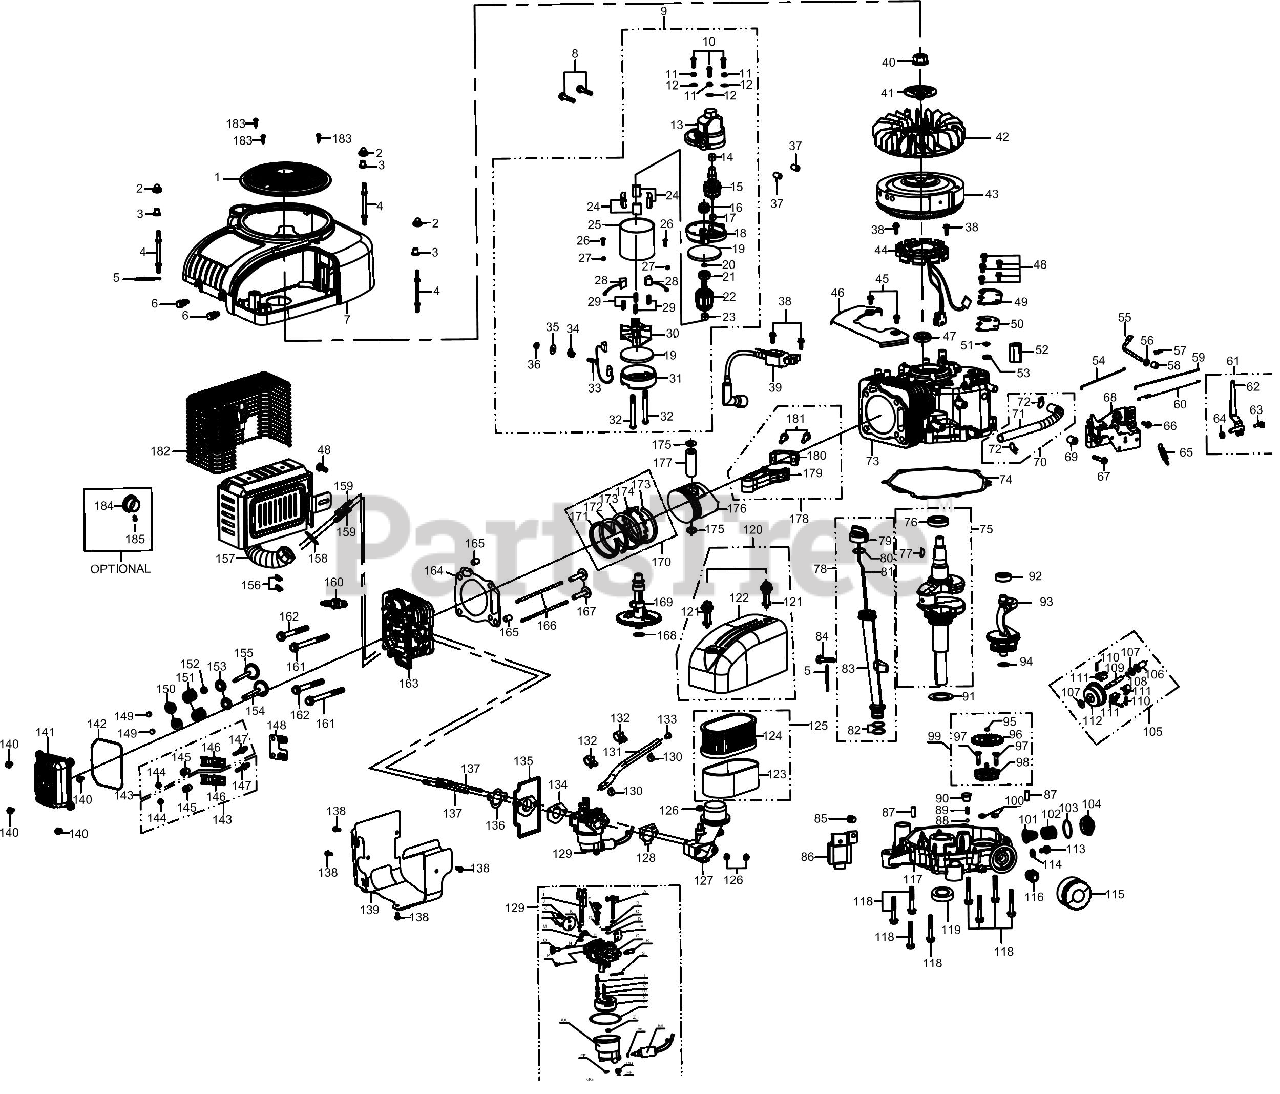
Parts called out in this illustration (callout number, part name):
1	Shroud
2	Nut,M6
3	Bush, 16x12-10x6.5
4	Stud, M6x99
5	Clip
7	Engine Shroud
8	Bolt, M8x40
9	Electric Starter
13	Electric Starter Cover
14	Bearing
15	One-way Clutch
16	Spline Gear
17	Bearing
18	Electric Starter Cover
22	Rotor
23	Bearing
24	Magnet
25	1P90 Case
28	Brush
29	Brush Spring
30	Brush Bracket
31	Cover
33	Anode Bolt
34	Wrapper
35	Insulator Board
37	Pin, 10x14
38	Bolt, M6x28
39	Ignition Module
40	Nut, M16x1.5
41	Cooling Fan Plate
42	Cooling Fan
43	Flywheel
44	Charging Coil
45	Bolt, M6x10
46	Shield
48	Bolt, M6x14
49	Breather Cover
50	Gasket, Breather Cover
51	Breather Valve
52	Breather Filter Screen
53	Second Air Valve Seat
54	Choke Lever
55	Governor Gear Shaft
57	Cotter Pin
59	Throttle Linkage
60	Idle Spring
61	Governor Lever Assembly
62	Governor Lever
64	Nut, M6
65	Governor Spring
66	Bolt, M6x18
67	Bolt, M6x38
68	Governor Gear Bracket Assembly
69	Bush, 6.5x15x20
70	Breather Hose
71	Breather Hose
73	Crankcase
74	Gasket, Crankcase
75	Crankshaft
76	Bearing, 6207
77	Woodruff Key
78	Dipstick
79	Dipstick Cover
80	O-Ring, 21.9x2.62
81	Dipstick
82	O-Ring, 21.2x2.8
83	Dipstick Seat
84	Bolt, M6x35
85	Earth Bolt
86	Regulator
87	Pin, 8x14
88	Ball S6.35
89	Spring
91	Washer, 35.4x2x54
92	Bearing, 6202
93	Balance Shaft
94	Washer, 15.4x1x25
95	Retaining Ring, 6
96	Oil Pump Gear
98	Oil Pump
99	Oil Pump
100	O-Ring, 10x2.65
101	Breather Filter Screen
102	Breather Spring
103	O-Ring, 35.5x2.65
104	Breather Cover
105	Governor Gear
106	Governor Cup
107	Washer, 6.5x1x13
108	Retaining Ring
109	Governor Shaft
110	Governor Shaft
111	Governor Fly Weight
112	Governor Gear
113	Bolt, M8x15
114	Washer, 8.3x1.5x17
115	Oil Filter
116	Connection Pipe
117	Crankcase Cover
118	Bolt, M8x54
120	Air Filter Cover Assembly
121	Air Filter Cover
122	Air Filter Cover
123	Air Filter Element
124	Air Filter
125	Heavy Duty Air Filter Kit
126	Wing Nut
127	Intake Manifold
128	Manifold Gasket
129	Carburetor
130	Clamp
131	Fuel Hose, 6.3x12.5x290
132	Clip
134	Gasket, Carburetor
135	Insulator
136	Gasket, Carburetor Insulator
137	Stud, M6-8x140
138	Bolt, M5x10
139	Shroud
140	Bolt, M6x22
141	Valve Cover
142	Gasket, Valve Cover
143	Rocker Arm Assembly
144	Lock Nut
145	Adjust Nut
146	Rocker Arm
148	Rocker Arm Base
149	Valve Adjust Cap, Exhaust
150	Valve Spring Seat
151	Valve Spring
153	Valve Spring Seat
154	Exhaust Valve
155	Intake Vavle
156	Nut, M8
157	Muffler
158	Gasket, Muffler
159	Stud, M8x47
160	Spark Plug
161	Bolt, M10x1.25x85
162	Bolt, M10x1.25x65
163	Cylinder Head
164	Gasket, Cylinder Head
165	Pin, 12x16
166	Push Rod
167	Tappet
168	Washer, 16.4x1x24
169	Camshaft
170	Piston Ring Set
173	Scraper Ring, Oil Ring
174	Lining Ring, Oil Ring
175	Circlip
176	Piston
177	Piston Pin
178	Connecting Rod Assembly
179	Connecting Rod
180	Connecting Rod Cap
181	Connecting Rod Bolt
182	Muffler Guard
183	Self-tappling Screw, ST5.5x25
184	Spark Arrester
185	Self-tappling Screw, ST5x8
A	Choke Shaft
B	Gasket
C	Choke Spring
D	Washer
E	Choke Plate
F	Idle Jet
H	Throttle Shaft Sleeve
I	Throttle Shaft
J	Throttle Plate
L	Washer, 3
M	Gasket, Throttle Shaft
N	Gasket
O	Idle Adjusting Screw
P	Idle Jet Rivet
Q	Carburetor Body
R	Fuel Nipple
S	Float Pin
T	Nozzle Tube
U	Needle Valve
V	Main Jet
W	Needle Valve Spring
X	Float
Y	O-Ring, Float Bowl
Z	Seal
AA	Float Bowl
BB	Solenoid Valve
CC	O-Ring, Solenoid Valve Seat
DD	Gasket, Drain Bolt
EE	Drain Bolt
FF	O-Ring, Solenoid Valve Seat
GG	Bolt
